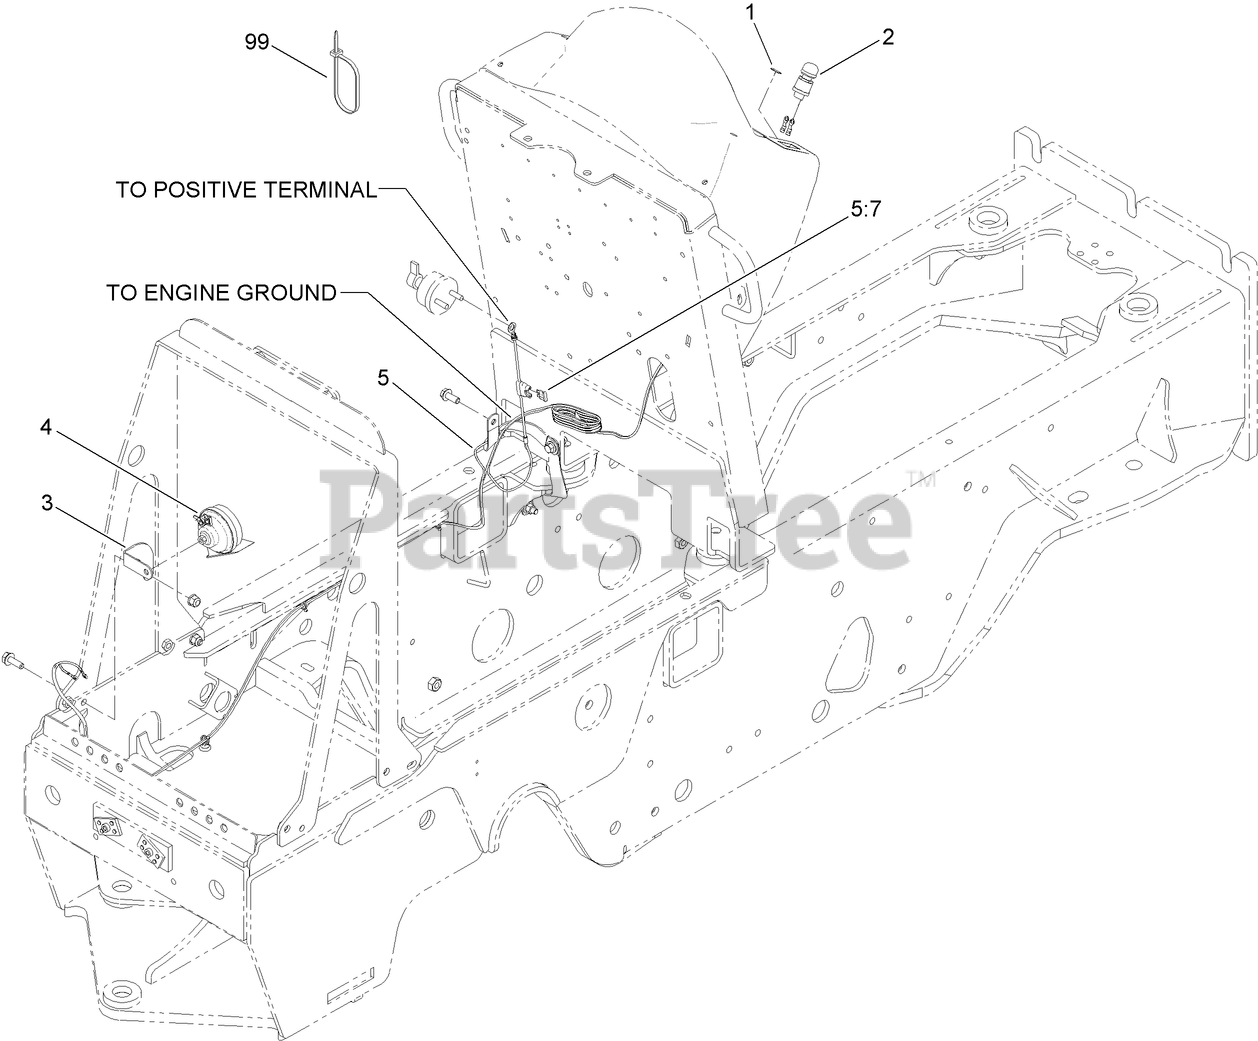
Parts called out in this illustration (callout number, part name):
1	Decal-Horn
2	SWITCH-PUSH BUTTON (SEALED)
3	BRACKET-MOUNTING, HORN
5	HARNESS-WIRE, HORN
5:7	FUSE-BLADE, 10 AMP
99	TIE-CABLE
